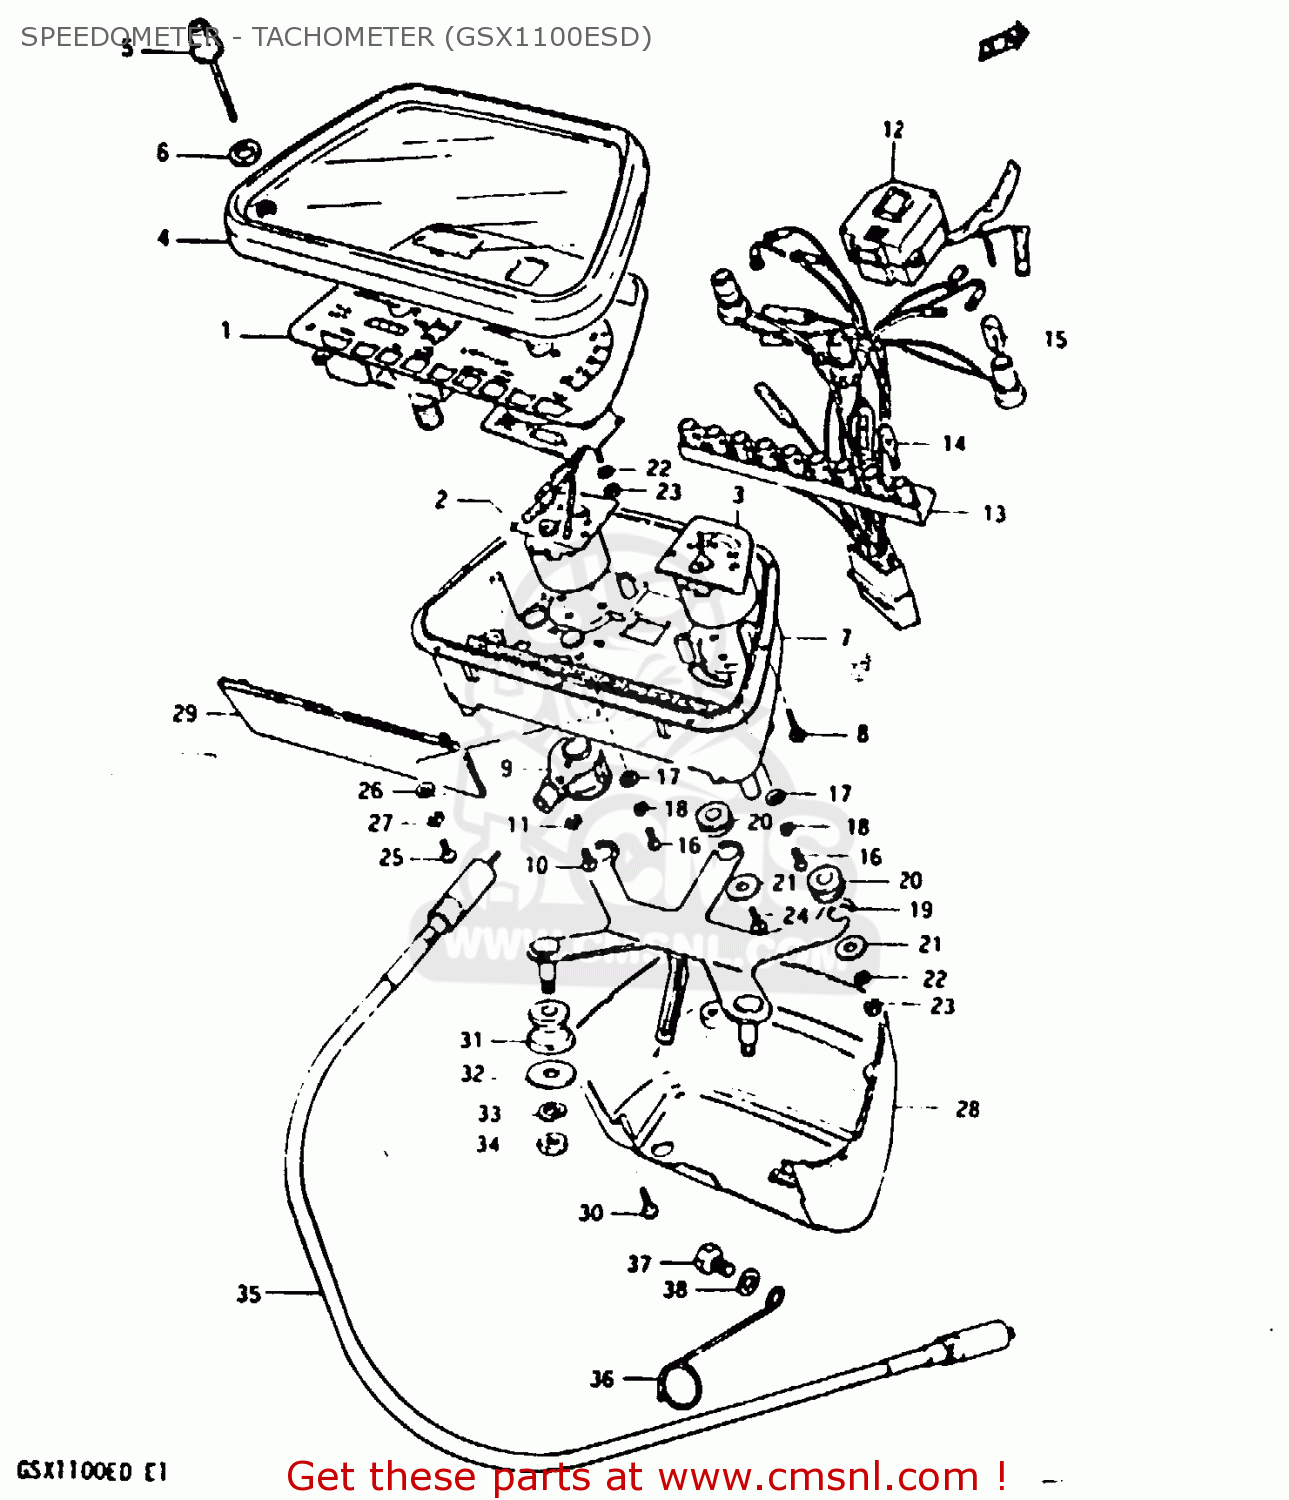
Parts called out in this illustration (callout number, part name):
1	SPEEDO & TACHOMETER (MILE/KILO)
2	METER,FUEL
3	METER,OIL TEMPERATURE
4	HOOD,METER
5	KNOB,TRIP METER
6	SEAL,TRIP KNOB
7	CASE,METER,INNER
8	SCREW
9	GEAR BOX,SPEEDOMETER
10	SCREW 4X10
11	LOCK WASHER
12	INDICATOR ASSEMBLY,GEAR POSITION
13	SOCKET UNIT,METER
14	BULB(12V3W,WB371,T7)
15	BULB(12V3.4W,T10,BF175-01450A)
16	SCREW 3X12
17	WASHER
18	LOCK WASHER
19	BRACKET,METER
20	CUSHION
21	WASHER,COMBINATION METER
22	WASHER
23	NUT 4MM
24	SCREW
25	SCREW
26	WASHER
27	LOCK WASHER
28	COVER,METER LWR
29	PLATE,COVER
30	SCREW
31	CUSHION,METER BRACKET
32	WASHER (8.5X20X1.6)
33	LOCK WASHER
34	NUT
35	CABLE ASSEMBLY,SPEEDOMETER
36	CLAMP,SPEEDOMETER CABLE
37	BOLT, UPPER
38	WASHER
